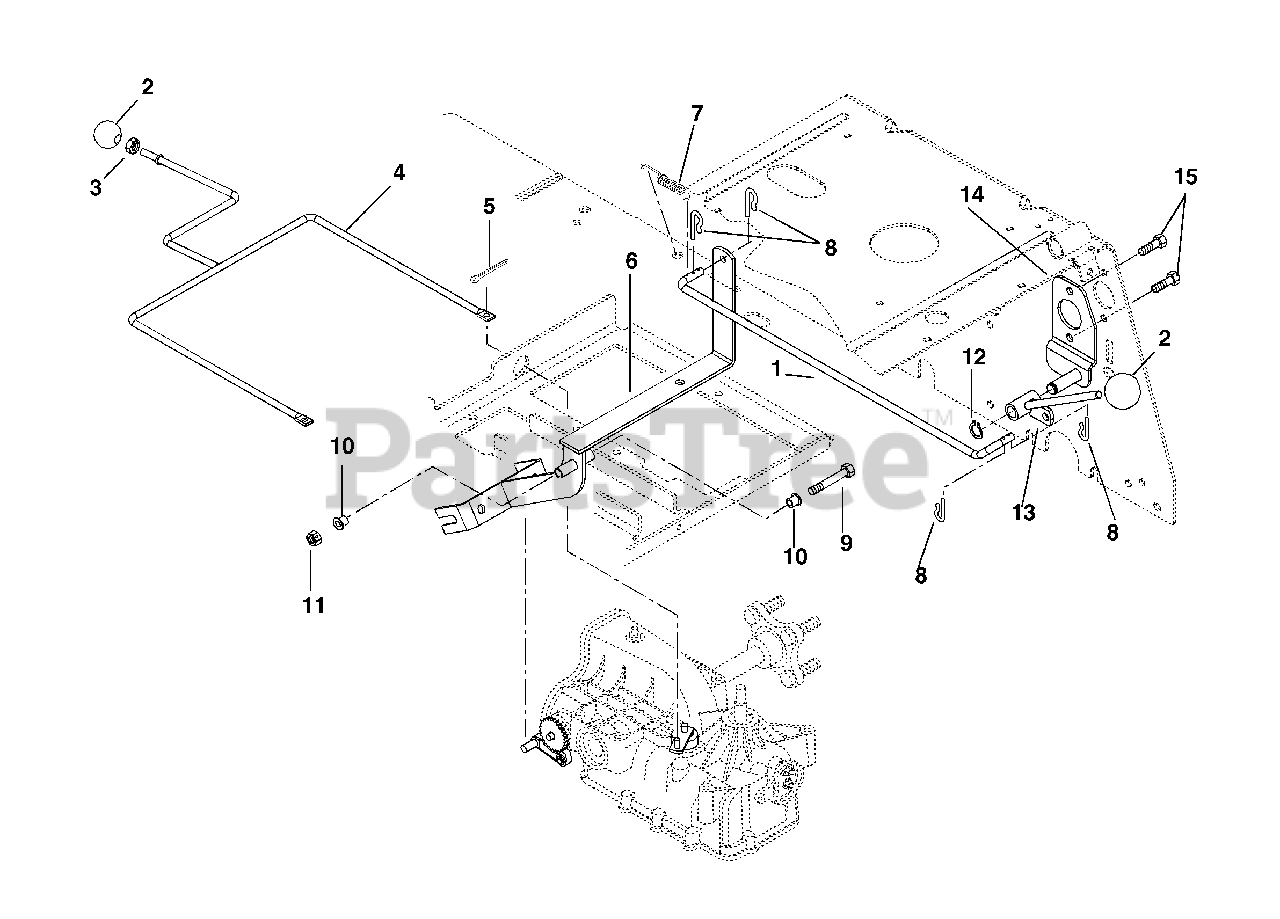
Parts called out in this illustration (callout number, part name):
1	ROD - BRAKE
2	KNOB, BALL 5/16-18 X 1.5
3	@NUT-HEX .31-18 YWZC
4	DUMP VALVE WELDMENT
5	PIN-HAIR INT .08X.18X1.18 YWZC
6	BRAKE WELDMENT
7	SG-TENS .051X.60X2.25 WLD 7.0
8	PIN-HAIR INT .08X.18X1.18 YWZC
9	@BLT-HEX .25-20X3.00 YWZC
10	BSHG-FLG .257X.38X1.080 NYL
11	@NUT-LK-CTR .25-20 YWZC
12	RG-RTNG-EXT .500X.050 (SNAP)
13	BRAKE LEVER
14	PIVOT - BRAKE LEVER
15	@BLT-HEX .31-18X1.00 GR5 YWZC
